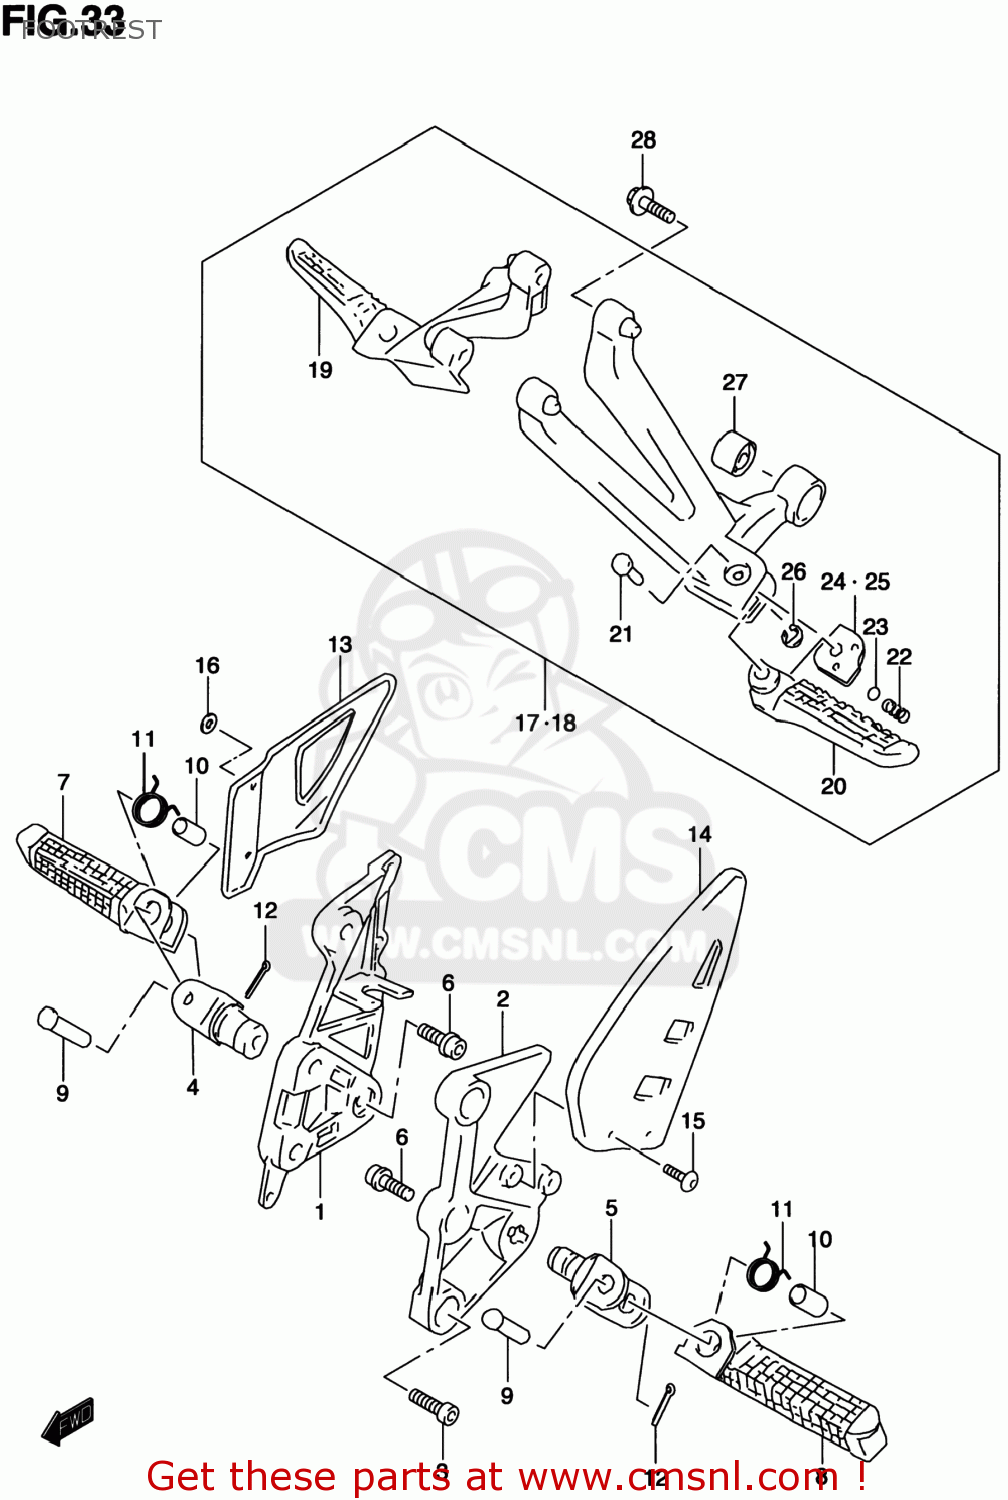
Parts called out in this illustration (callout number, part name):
1	BRACKET,FR FOOTREST,R
2	BRACKET,FR FOOTREST,L
3	BOLT
4	HOLDER,FOOTREST,R
5	HOLDER,FOOTREST,L
6	BOLT(10X28)
7	BAR,FR FOOTREST,R
8	BAR,FR FOOTREST,L
9	PIN
10	SPACER(8.1X12X22)
11	SPRING
12	PIN 20X15
13	GUARD,FR FOOTREST,R
14	GUARD,FR FOOTREST,L
15	SCREW(5X10)
16	WASHER(6.5X16X1)
17	FOOTREST ASSY,PILLION,R
18	FOOTREST ASSY,PILLION,L
19	BAR,PILLION FOOTREST,R
20	BAR,PILLION FOOTREST,L
21	PIN
22	SPRING
23	BALL
24	PLATE,PILLION FOOT,R
25	PLATE,PILLION,LEFT
26	E-RING
27	BUSH
28	BOLT
